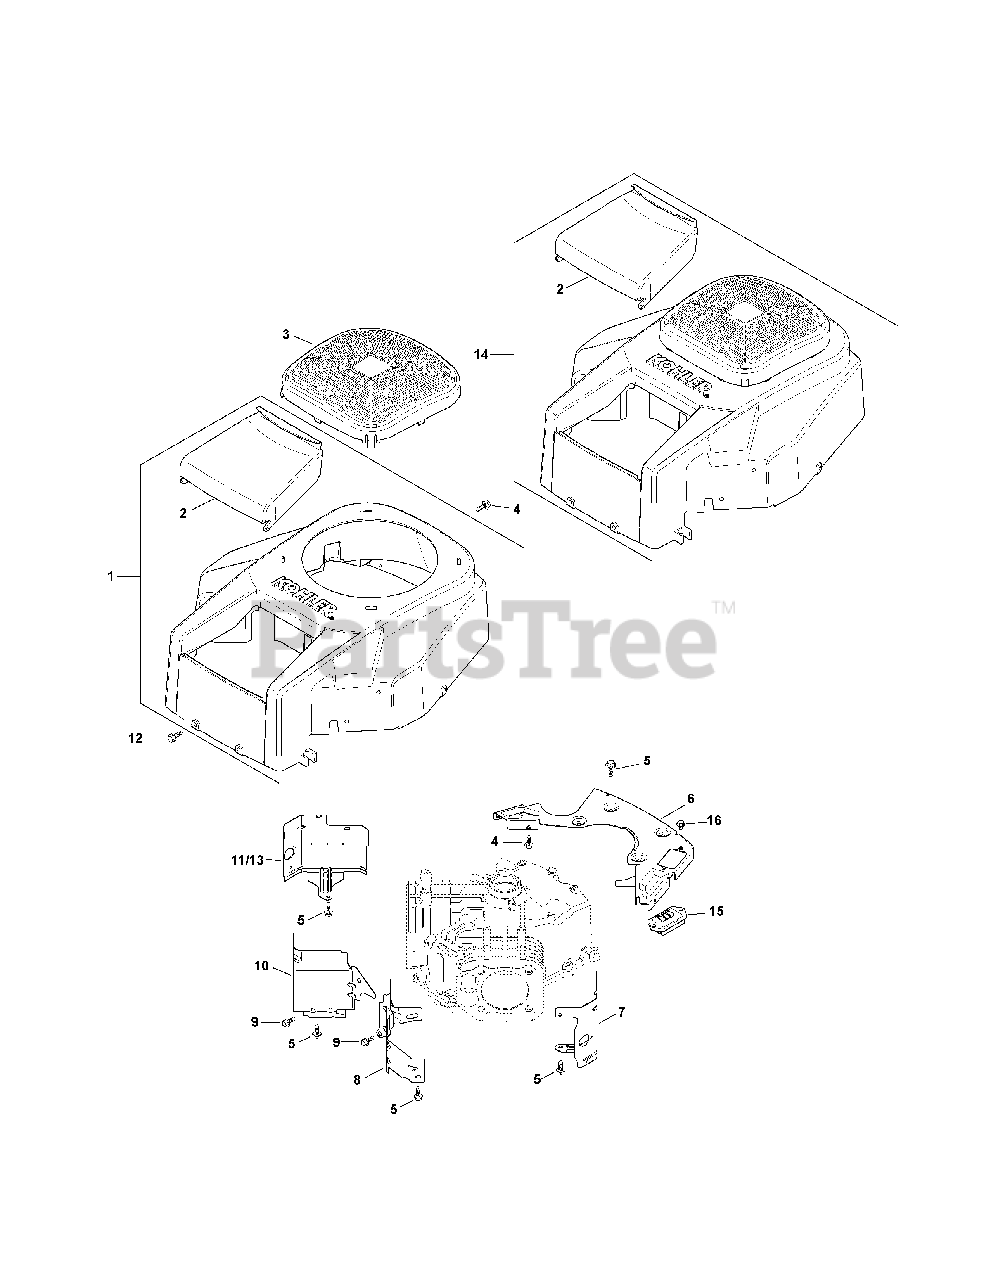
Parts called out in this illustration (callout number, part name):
1	Housing Blower Kit
2	Air Cleaner Cover
4	Flg. Thd. Frm. Screw, M5 x 0.8 x 16
5	Flg. Thd. Frm. Screw, M6 x 1.0 x 16
6	Backing Plate Kit
7	Cyl Barrel Baffle - #2 Side
8	Valley Baffle - #2 Side
9	Flg. Thd. Frm. Screw, M5 x .8 x 10
10	Valley Baffle - #1 Side
11	Cyl Barrel Baffle - #1 Side
12	Tap Screw, M6 x 1.7 x 18
15	Regulator/Rectifier
16	Flng. Thd. Frm. Screw, M6 x 1.0 x 10
